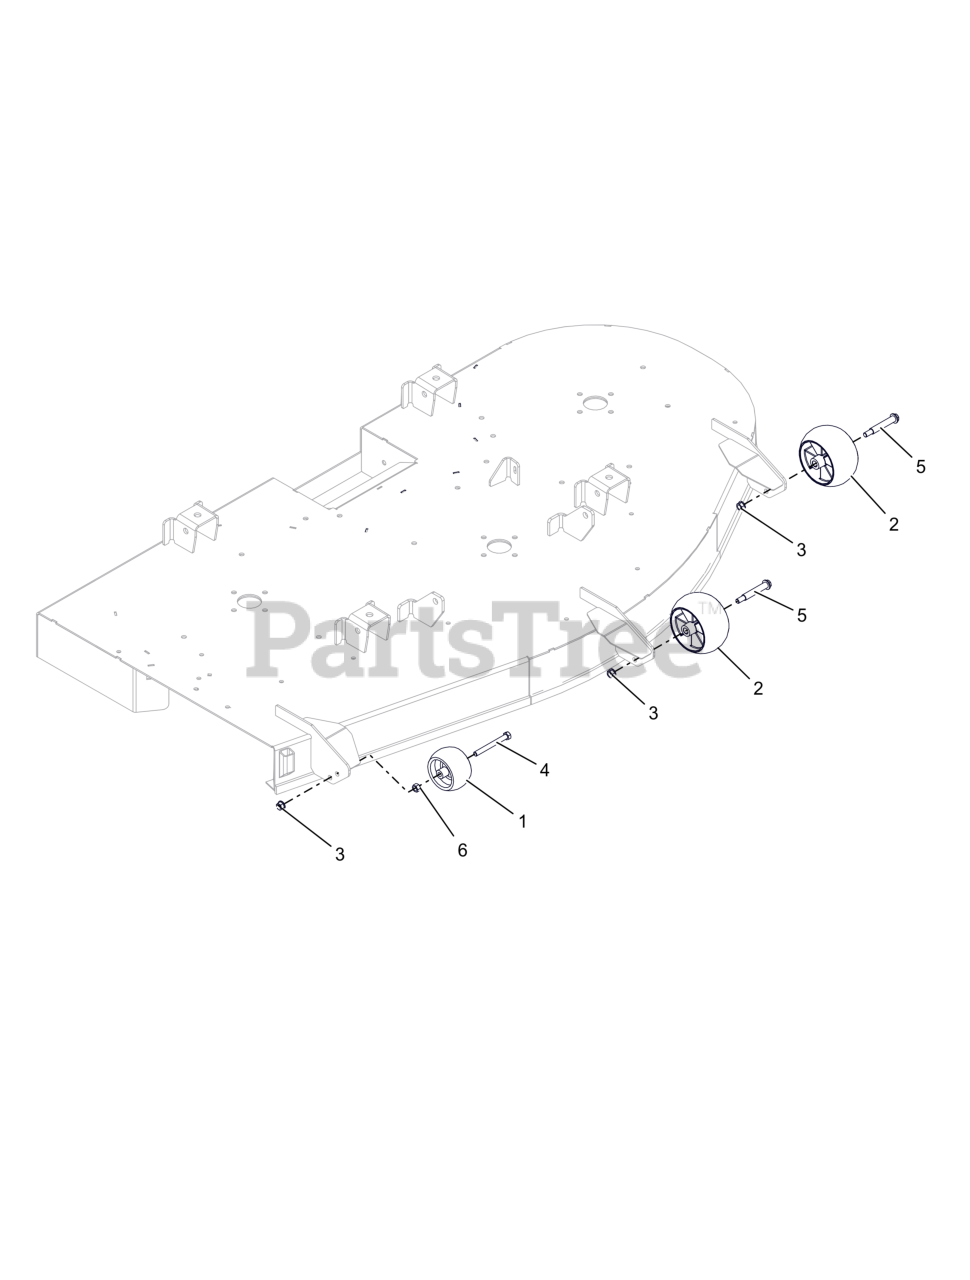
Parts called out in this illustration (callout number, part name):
2	ANTI-SCALP WHEEL - 5X OS
3	NUT-LK-CTR-FLG .375-16 GF ZCC
4	BLT, HEX .38-16X3.50 G5 ZCC
5	BLT-SHLDR .38-16X2.50 HWH G5
6	NUT-STD .375-16 G2 ZCC
